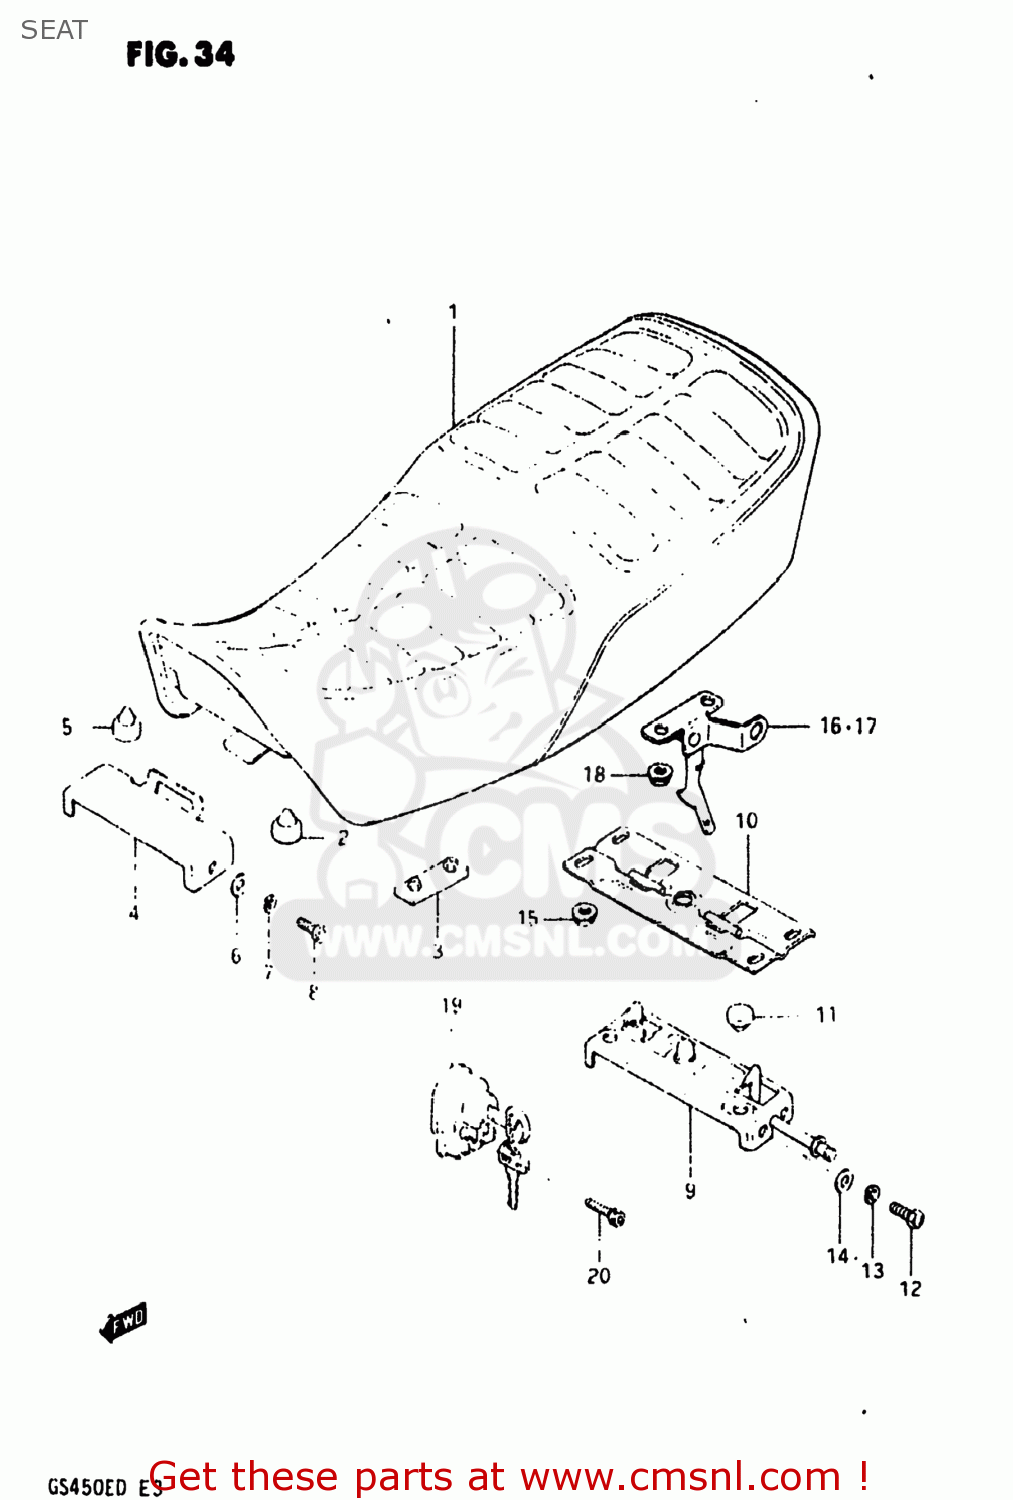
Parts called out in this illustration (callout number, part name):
1	SEAT ASSEMBLY
2	CUSHION
3	CUSHION
4	PLATE,SEAT LOCK,FRONT
5	CUSHION(11.5X22X20)
6	WASHER
7	LOCK WASHER
8	BOLT
9	PLATE,CLAMP GUIDE
10	PLATE,SEAT CLAMP GUIDE
11	CUSHION
12	SCREW
13	LOCK WASHER
14	WASHER
15	NUT
16	LEVER,SEAT HOOK,RIGHT
17	LEVER,SEAT HOOK,LEFT
18	NUT
19	LOCK ASSY,HELMET
20	BOLT 5X25
